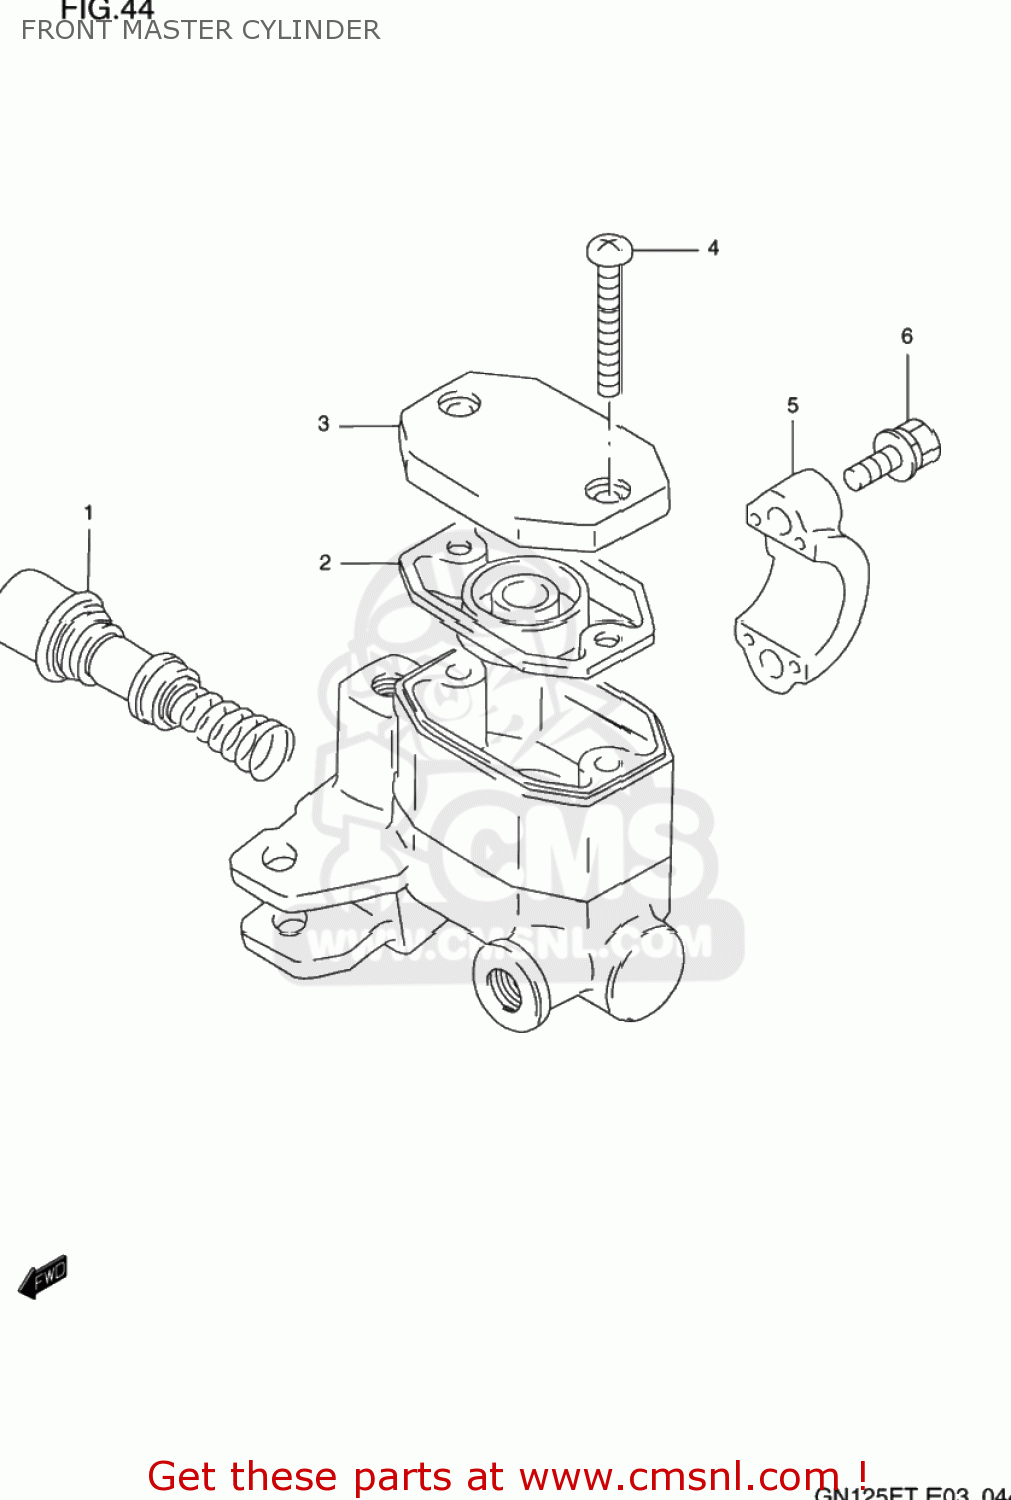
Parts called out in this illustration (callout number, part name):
1	PISTON & CUP SET
2	DIAPHRAGM
3	CAP
4	SCREW
5	HOLDER
6	BOLT
